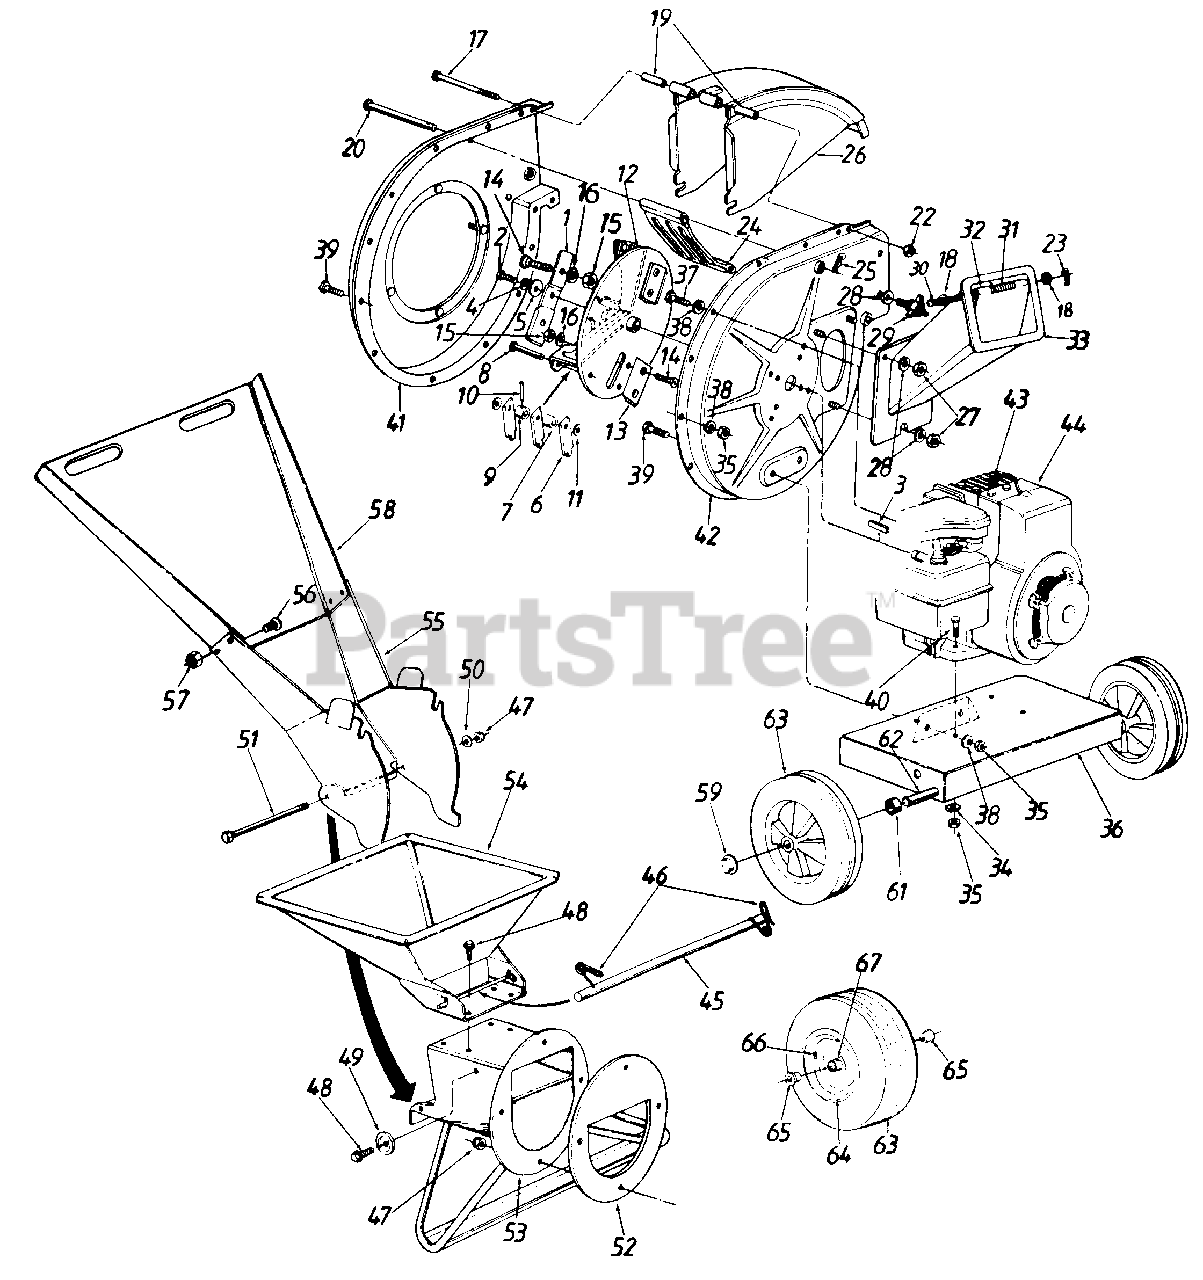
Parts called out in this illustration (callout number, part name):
1	Blade
3	Sq. Key 1/4 x 2.0" Lg.
4	L-Wash. 3/8" I.D. H.D.
5	Fl-Wash. .406" I.D. x 1.25" O.D. Hdn.
6	Flail
7	Flail Spacer
8	Clevis Pin .496" Dia.
9	Flail Spacer w/.160" Dia. Hole
10	Spring Roll Pin 1.12" Lg.
11	Fl-Wash. .531" I.D. x .94" O.D.
12	Impeller Ass'y.
13	Chipper Blade
14	Flat Hd. Scr. 5/16-24 x .75" Lg.
15	Hex Top L-Nut 5/16-24 (Gr. 5)
16	L-Wash. 5/16" I.D.
17	Hex Bolt 1/4-20 x 3.75" Lg.
18	Fl-Wash. .281" I.D. x .5" O.D.
19	Chute Hinge Spacer 1.66" Lg.
20	Clevis Pin .5" Dia. x 4.62" Lg.
22	Hex Ctr. L-Nut 1/4-20 Thd.
23	Cotter Pin 3/32" x 5/8"
25	Internal Cotter Pin 3/8" Dia.
27	Hex Nut 5/16-18 Thd. (Gr. 5)
28	Bell-Wash. .345" I.D. x .88"
29	Hand Knob
30	Chipper Door Rod
31	Torsion Spring 1.14" Lg.
35	Hex Nut 5/16-18 Thd. (Gr. 5)
36	Shredder Frame
37	Hex Bolt 5/16-24 x .75" Lg.
38	L-Wash. 5/16" I.D.
39	Hex Bolt 5/16-18 x .75" Lg. (Gr. 5)
40	Hex Bolt 5/16-18 x 1.75" Lg.
42	Flail Housing Ass'y.--R.H.
43	Spark Plug Boot
44	Engine
45	Release Bar
46	Torsion Spring 1.06" Lg.
47	Elastic Lock Nut 5/16-18 Thd.
48	Hex Wash. Hd. Self-Tap Scr. 5/16-18 x .75" Lg.
49	Stop Washer
50	Fl-Wash. 5/16" I.D.
51	Hex Bolt 5/16-18 x 8.38" Lg.
57	Hex L-Nut 1/4-20 Thd.
61	Spacer .64" I.D. x .38" Lg.
62	Shredder Axle
63	Wheel Ass'y. Comp.
64	Rim Only
65	Flange Bearing .632" I.D.
66	Air Valve
67	Grease Fitting
